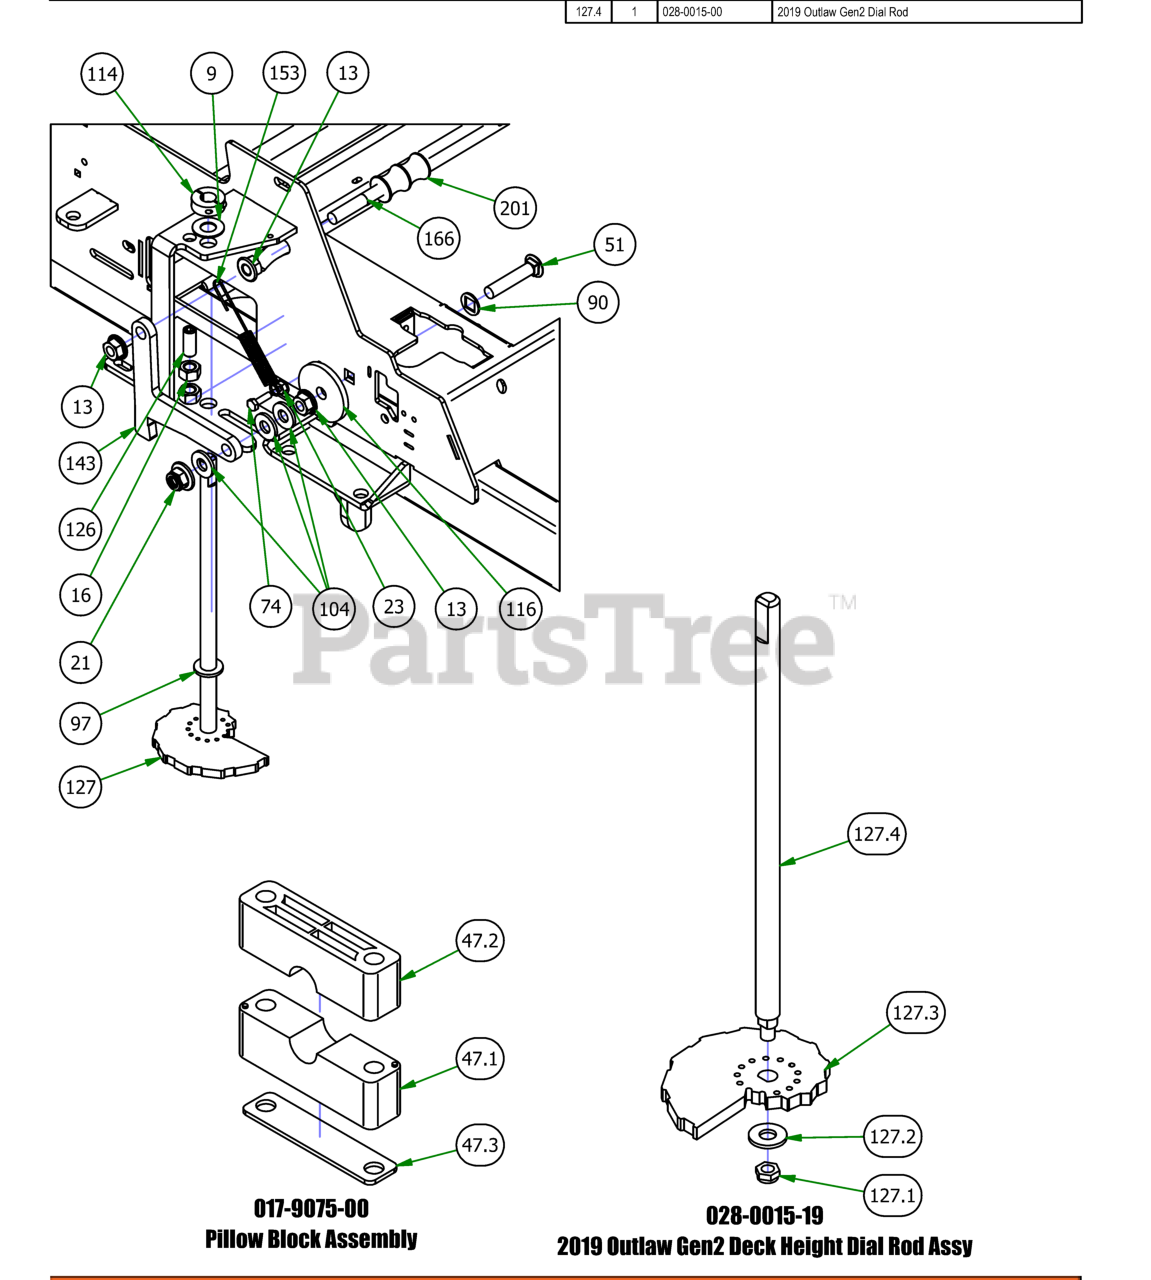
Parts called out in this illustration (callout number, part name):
9	.625 ID x 1.250 OD x .062 THK F/W Nylon
13	1/2" Flange Nut
16	1/2" Hex Nut
21	1/2-13 NYLON INSERT FLANGE LOCKNUT ZINC
23	1/4-20 Hex Flange Nuts Zinc w/Serrations
47.1	Two Piece Pillow Block (Male)
47.2	Two Piece Pillow Block (Female)
47.3	Two Piece Pillow Block Strap
51	1/2 x 2-1/2 Carriage Bolt
74	1/4-20 x 1-1/4 GR 5 Hex Bolt
90	.517 Square Hole Round Washer
97	.630 ID Plastic Washer
104	.505 Nylon Spacer
114	5/8" Split Collar
116	MZ Deck Idler Spacer
126	Dial Rod Plunger
127	2019 Outlaw Gen2 Deck Height Dial Rod Assy
127.1	3/8-24 Nylon Insert jam locknut
127.2	3/8" Flat Washer
127.3	2019 Deck Height Cam
127.4	2019 Outlaw Gen2 Dial Rod
143	2019 Outlaw Deck Travel Lock
153	Brake Spring
166	Seat Bracket Pin
201	Travel Lock Rubber Grip
